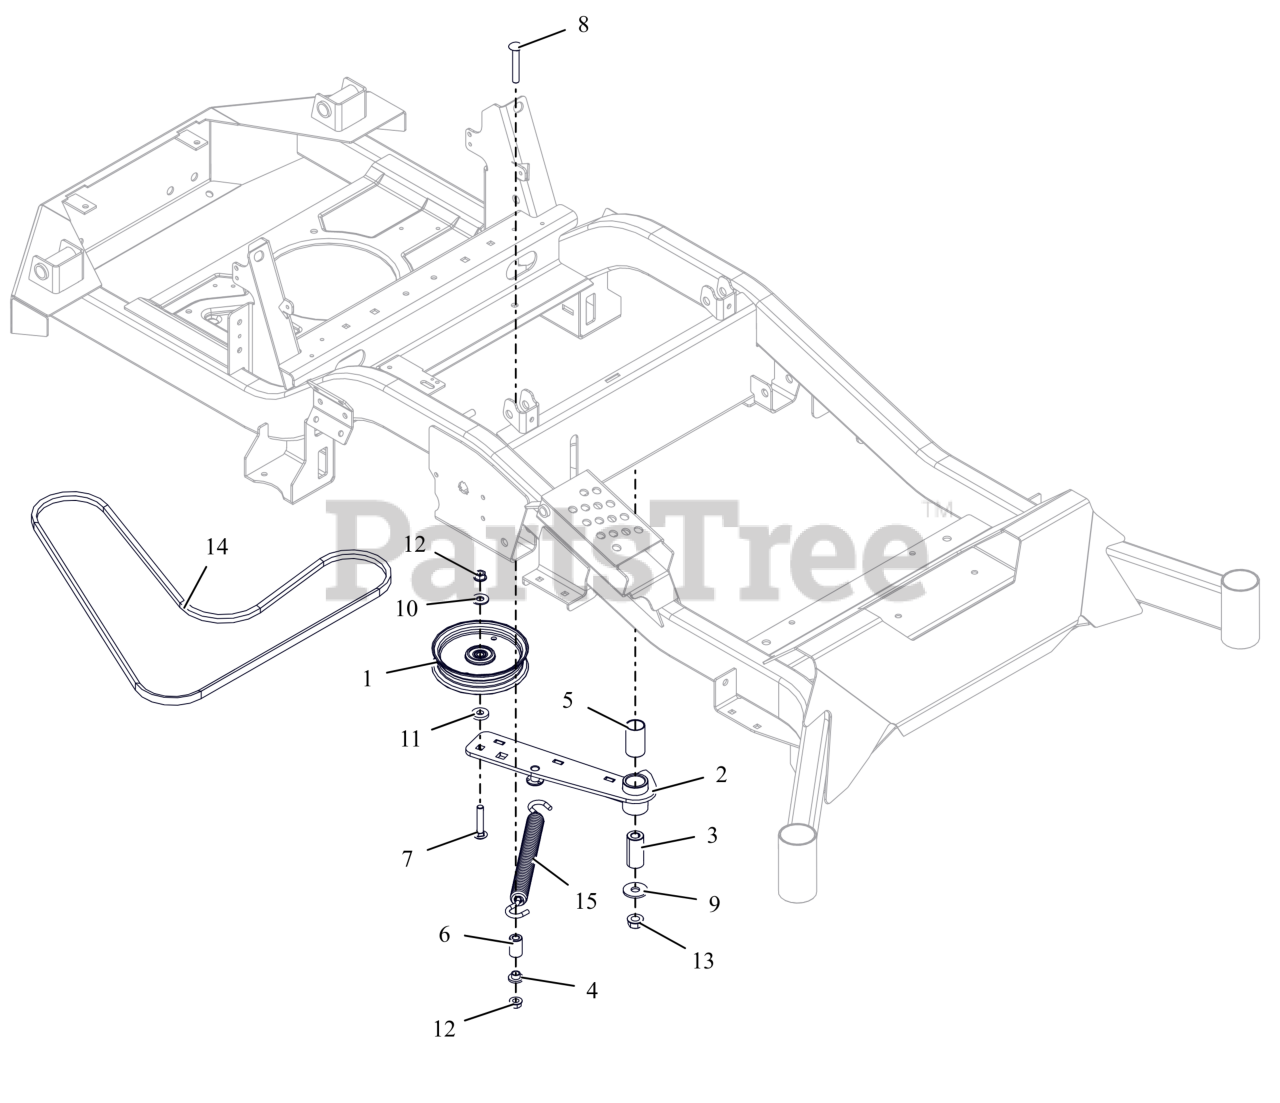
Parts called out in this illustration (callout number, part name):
1	IDLER- FLAT - 5.00" X .75"
2	WLDMT, HYDRO DRIVE IDLER ARM (BLACK)
3	BSHG, SPCR .502X.997X2.03 PM
4	BSHG-FLG .385X.500X.875X.406
5	BSHG, 1.00X1.125X1.937
6	BUSHING, SLV .380X.750X1.190
7	BLT, RHSN .38-16X2.00 G5 ZCC
8	BLT, RHSSN.38-16X2.50 G5 ZCC
9	WSHR-FL-STL.511X1.44X.125ZC120
10	WSHR,FLT .438X1.00X.083 ZCC
11	WSHR, FLT .406X1.00X.188 ZCC
12	NUT-LK-TOP-FLG .38-16 ZC120
13	NUT-LK-TOP-FLG .500-13 GF ZCC
14	V-BELT, 4L-WRAPPED
15	SPRING, EXTENSION
